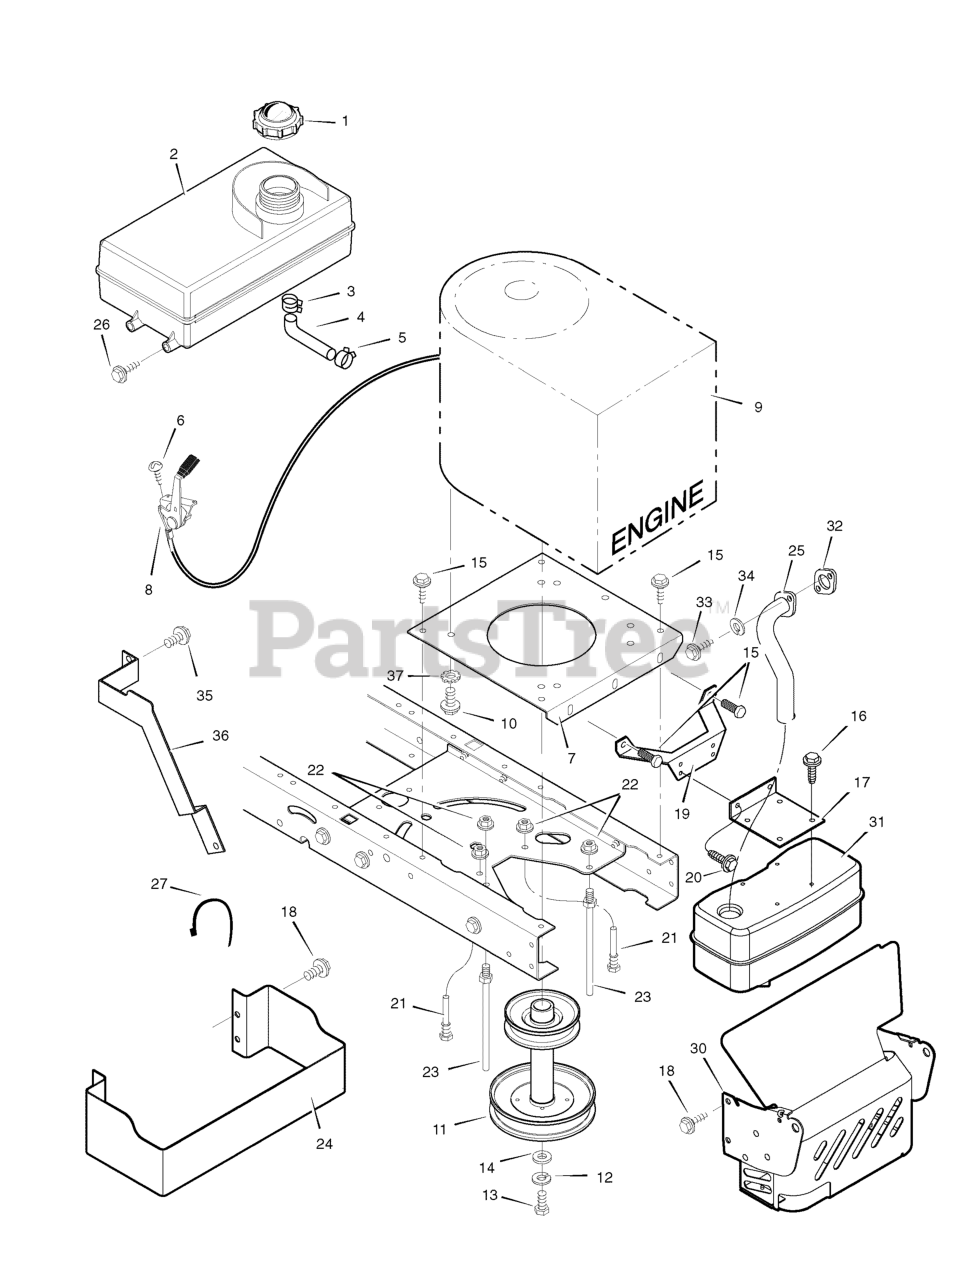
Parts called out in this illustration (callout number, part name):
1	Fuel Cap
2	TANK, Fuel 1.4 Gal.
3	Hose Clamp
4	Fuel Line (Must cut to length)
5	Hose Clamp
7	Plate, Engine
8	Throttle Control
9	Engine, Briggs & Stratton *
10	Bolt, Engine Mount
11	STACK PULLEY ASSEMBLY
12	Lockwasher
13	Bolt, Hex
17	Bracket, Muffler
19	Bracket, Muffler Mount
21	Guide, Belt
22	Nut, Flange
23	Guide, Belt
24	GUARD, Heat Shield
25	Exhaust Tube, Single
27	Tie Strap
30	Shield, Heat
31	Muffler
32	GASKET, Exhaust
34	Washer
35	Bolt, Washer Hex Head
36	Guard, Exhaust Pipe
37	Washer, Star
